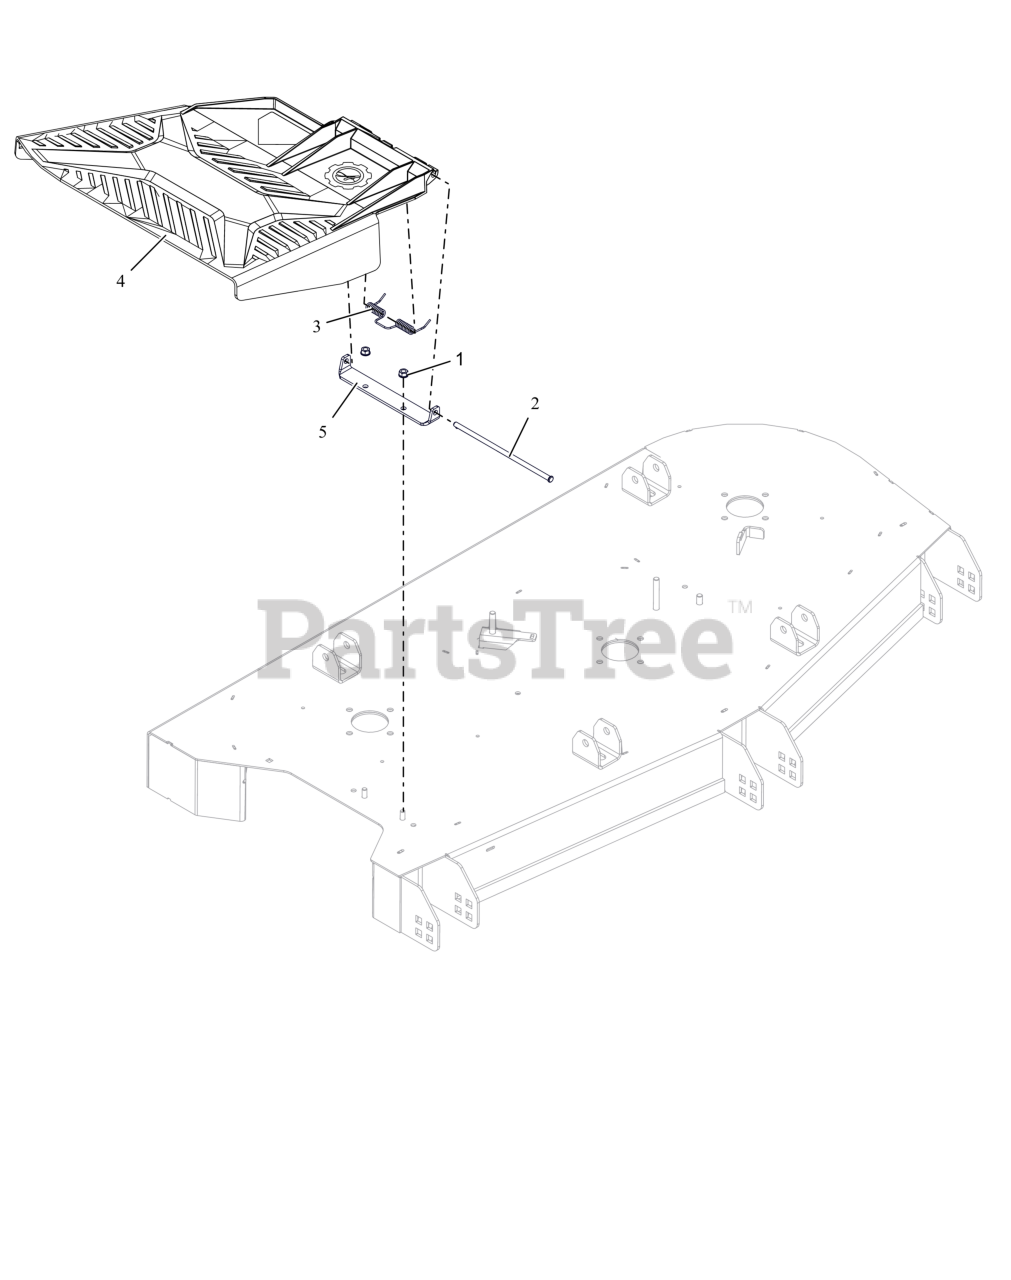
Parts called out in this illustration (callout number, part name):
1	NUT,LK-CTR-FLG .31-18 GF ZCC
2	PIN- SLIC .312X8.50
3	SPRING-TORSION
4	CHUTE- SIDE DISCHARGE
5	BRKT- DISCHARGE CHUTE-ARIENS
